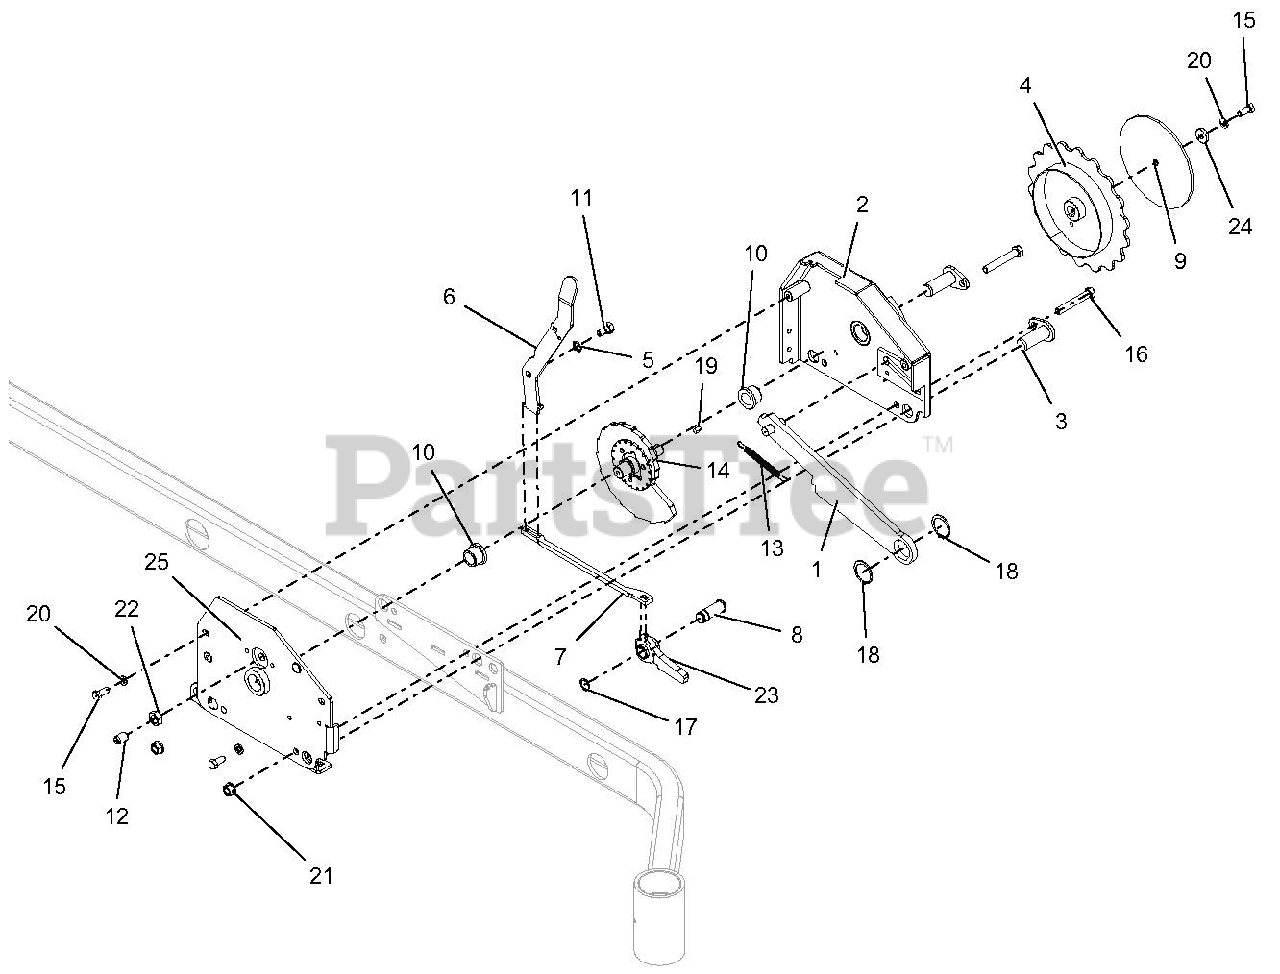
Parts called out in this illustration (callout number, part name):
1	WLDMT, HOC LINK
2	WLDMT, HOC INNER
3	WLDMT, PIN
4	WLDMT, DIAL, HOC
5	WAVE WASHER .390X.655X.110
6	LEVER, TRANSPORT LOCK
7	LINK, TRANSPORT LOCK
8	PIN, CLEVIS .625 SNAP RING
9	PLATE, DIAL-RED
10	BUSHING, FLANGE
11	BOLT, SHLDR .38-16 x .437 HEX YZ
12	BALL SPRING PLUNGER, .500-13
13	SPRG, EXTENSION
14	WLDMT, CAM HOC
15	BLT-HEX .31-18X.75 GR5 YWZC
16	BLT-HEX .38-16X2.50 GR5 YWZC
17	RG-RTNG-EXT .625x.050
18	RG-RTNG-EXT 1.25x.050
19	KEY-SQ .188X.188X.375
20	WSHR-LK .31X.078 REG YWZC
21	NUT, LK-CTR-FLG .38-16 YWZC
22	NUT, JAM .500-13 YWZC
23	WLDMT, LOCK PAWL
24	WSHR-FL-STL .328X.87X.179 YWZC
25	WLDMT, HOC OUTER
